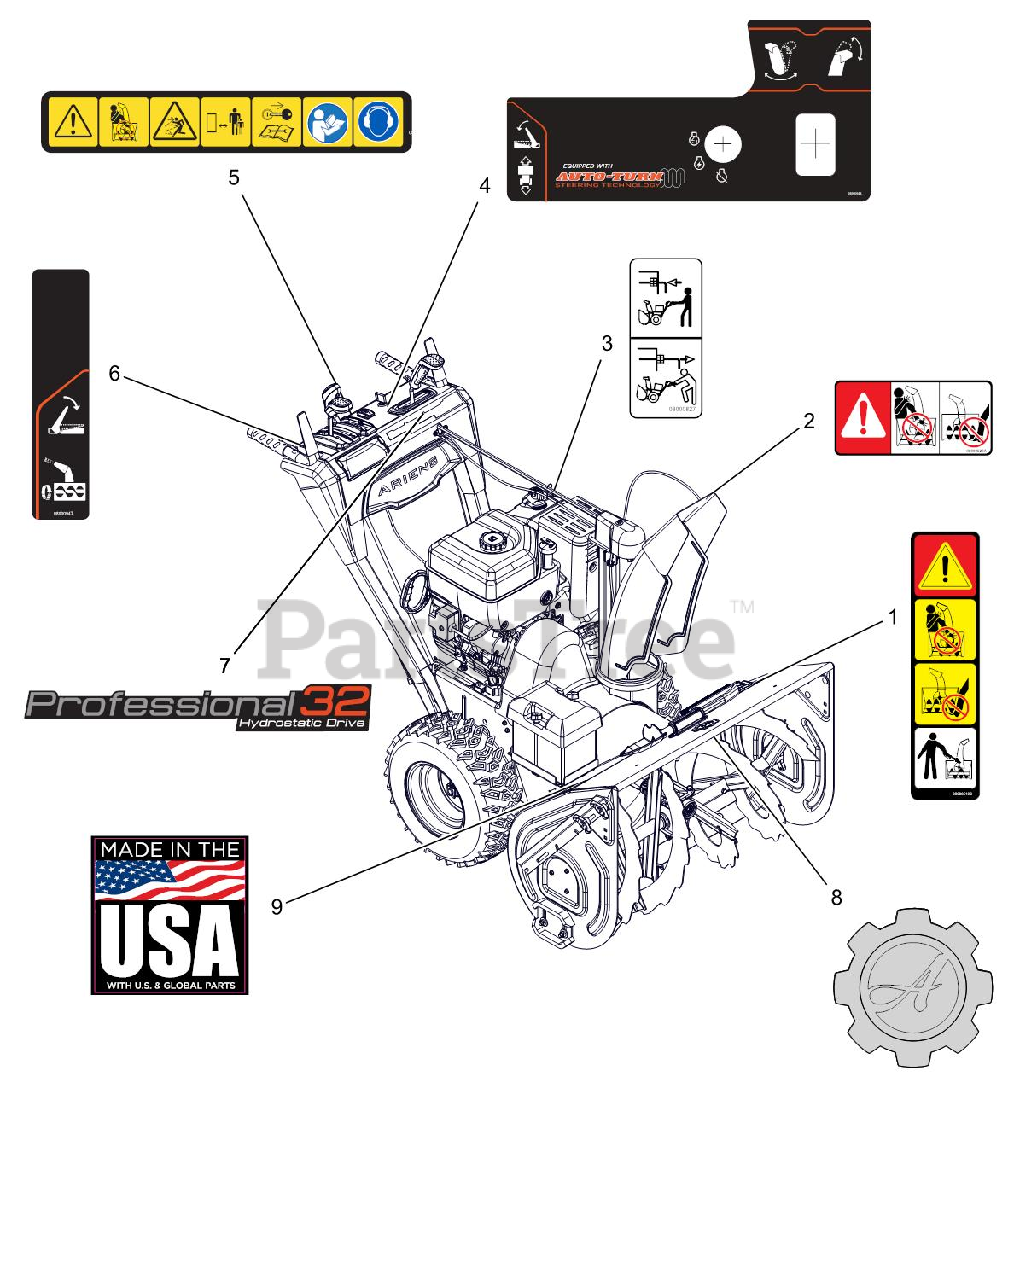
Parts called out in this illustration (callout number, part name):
1	DECAL, DANGER - ROTATING PARTS
2	DECAL, DANGER
3	DECAL, BYPASS
4	DECAL,CONTROL-LG QT2 12V
5	DECAL,DASH - SAFETY
6	DECAL,CONTROL-RH CONTROL
7	DECAL, DASH - PRO HYDRO 32
8	DECAL, ARIENS-GEAR BADGE
9	DECAL, MADE IN USA
